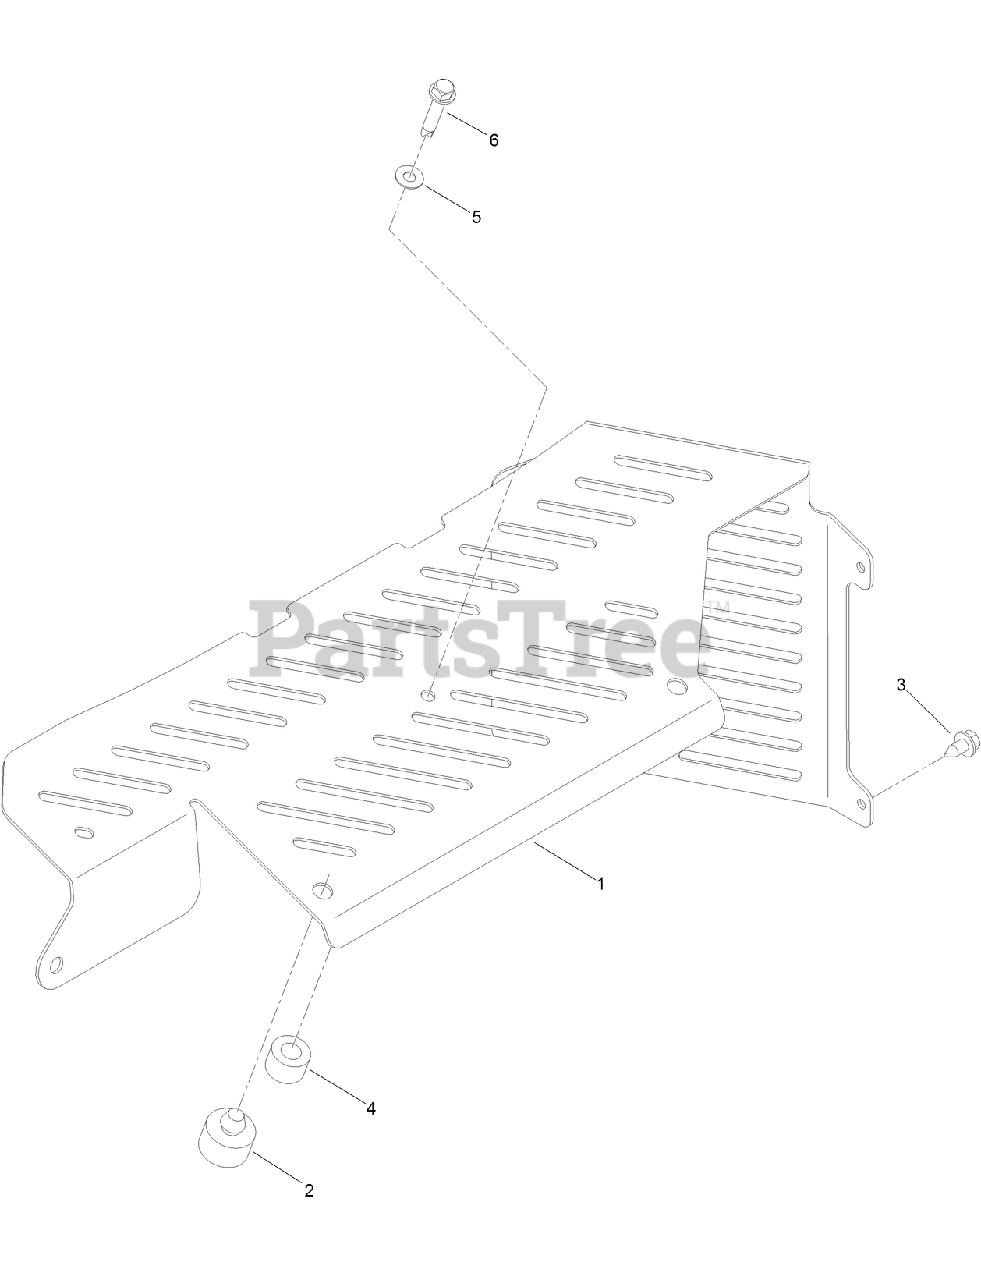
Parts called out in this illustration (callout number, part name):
1	LEAF GUARD
2	BUMPER-GROMMET
3	SCREW-HWHTF
4	SPACER-NYLON
5	WASHER-NYLON
6	SCREW-HWH THD CUT
